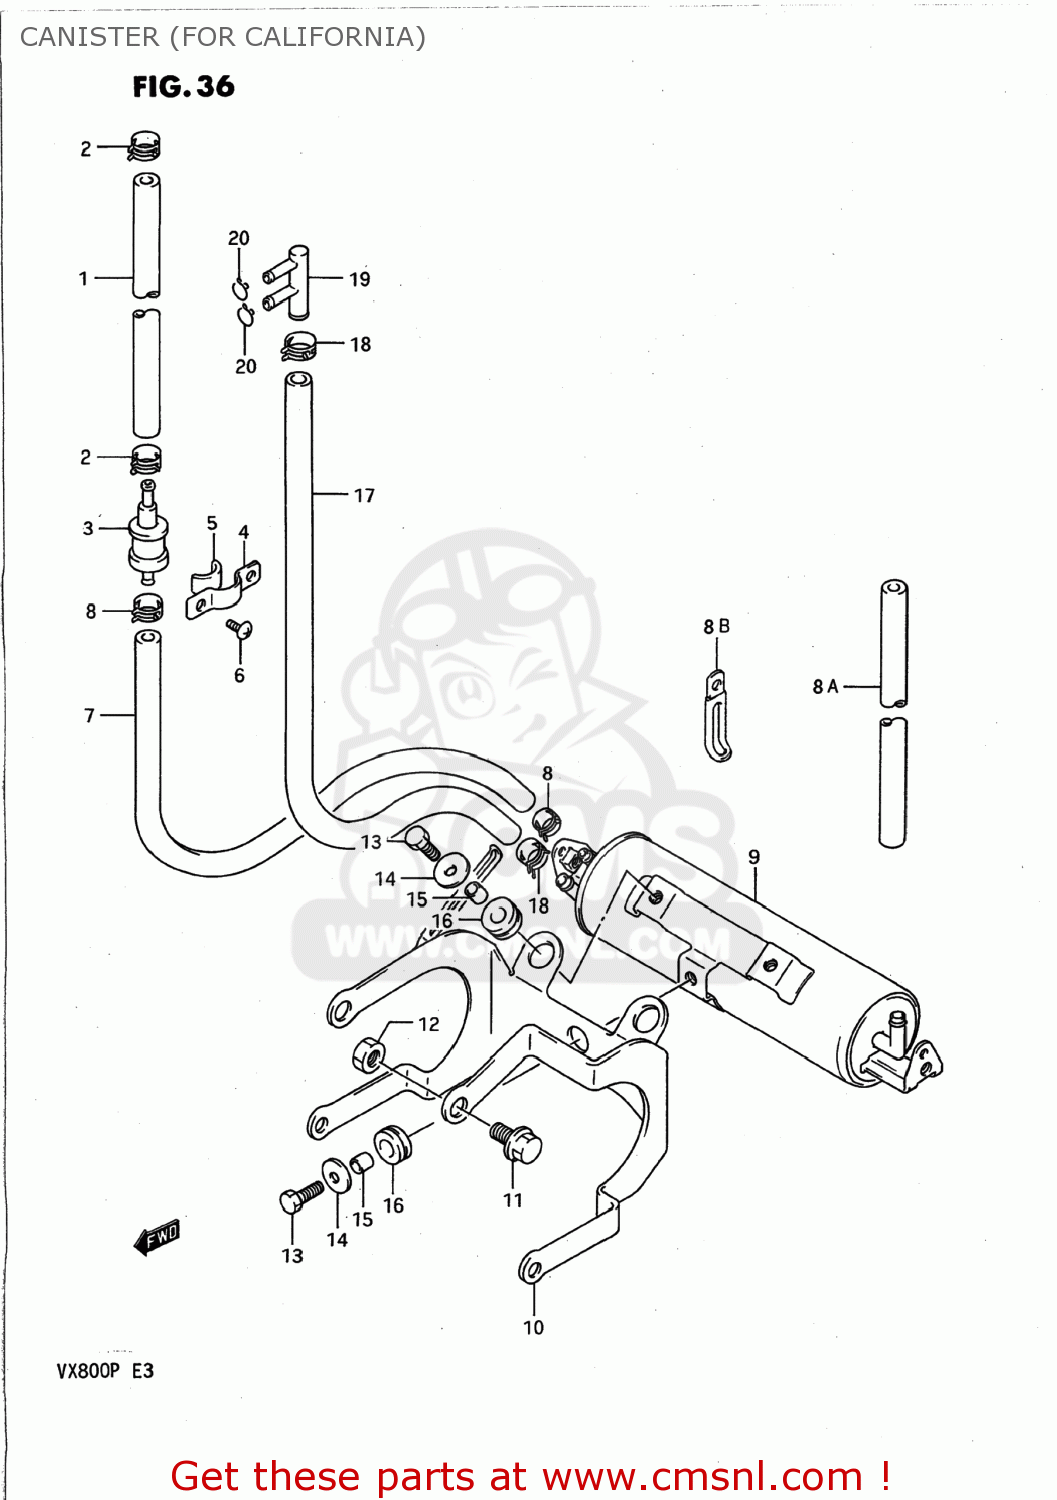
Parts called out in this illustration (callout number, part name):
1	HOSE
2	(CA) CLIP
3	VALVE,FUEL TANK BREATHER
4	PLATE,FUEL TANK BREATHER NO.2
5	CUSHION
6	SCREW
7	HOSE
8	(CA) CLIP
8A	HOSE
8B	CLAMP
9	(CA) CANISTER ASSEMBLY,CHARCOAL
10	PLATE COMP,CANISTER FITTING
11	BOLT
12	NUT
13	BOLT
14	WASHER
15	SPACER
16	CUSHION
17	HOSE(7X11X600)
18	CLAMP
19	SEPARATOR
20	CLIP
